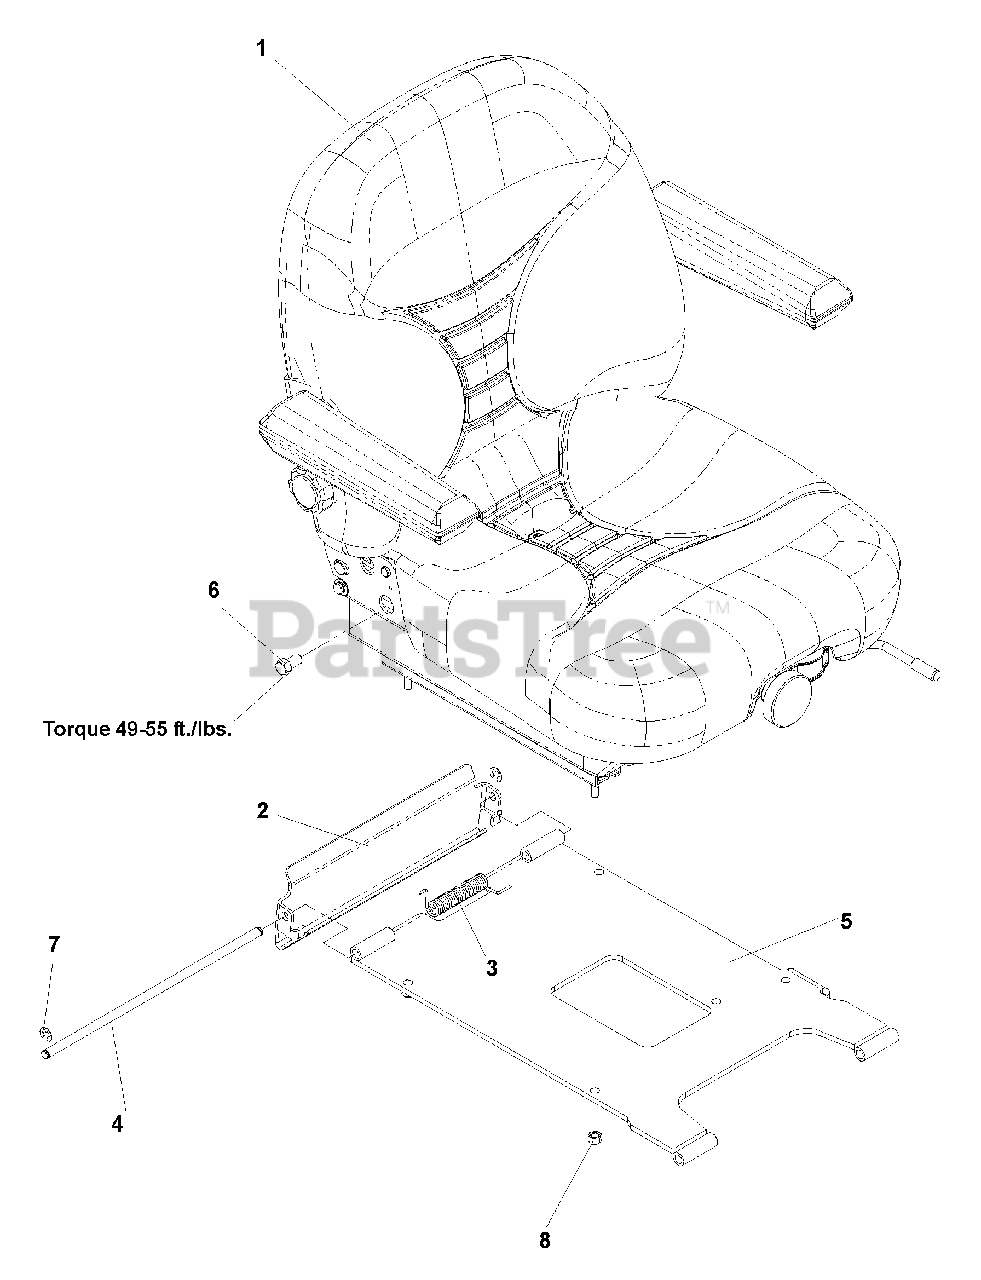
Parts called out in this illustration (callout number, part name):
1	SEAT, SUSPENSION
2	SEAT LATCH BRACKET
3	TORISON SPRING
4	SEAT LATCH ROD
5	SEAT MOUNT
6	HCS, 7/16-20 X 3/4, GR5
7	RING-RETAINING
8	NUT, 5/16-18, NYLOC
